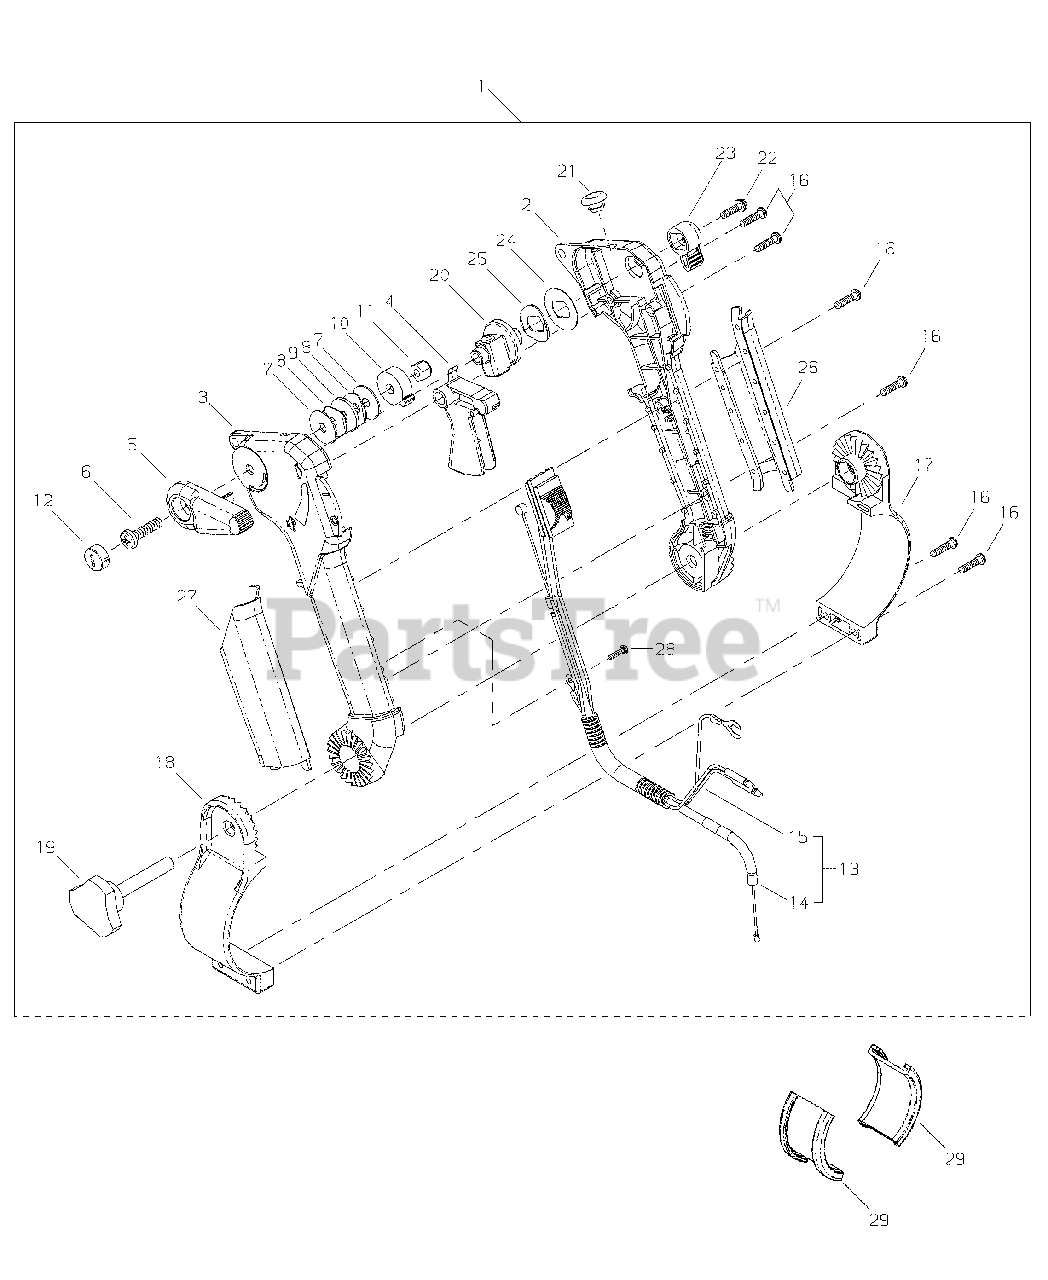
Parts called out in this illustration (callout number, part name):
1	THROTTLE LEVER ASSY
2	HANDLE, CONTROL - RIGHT
3	HANDLE, CONTROL - LEFT
4	TRIGGER, THROTTLE
5	LEVER, LOCK
6	ADJUSTABLE BOLT
7	WASHER - 6
8	LOCKWASHER
9	WASHER - 6
10	PLATE
11	NUT - 6 -- NYLON
12	CRUISE CONTROL BOLT CAP
13	THROTTLE CONTROL ASSY
14	CABLE, THROTTLE
15	SWITCH, IGNITION
16	SCREW
17	BRACKET, HANDLE - RIGHT
18	BRACKET, HANDLE - LEFT
19	KNOB, FASTENER
20	ADJUSTER ASSY
21	PLUG
22	SCREW, METERING LEVER PIN
23	SCREW, METERING LEVER PIN
24	WASHER
25	WASHER - SPRING
26	GRIP - RIGHT
27	GRIP - LEFT
28	SCREW - 3
29	SPACER
